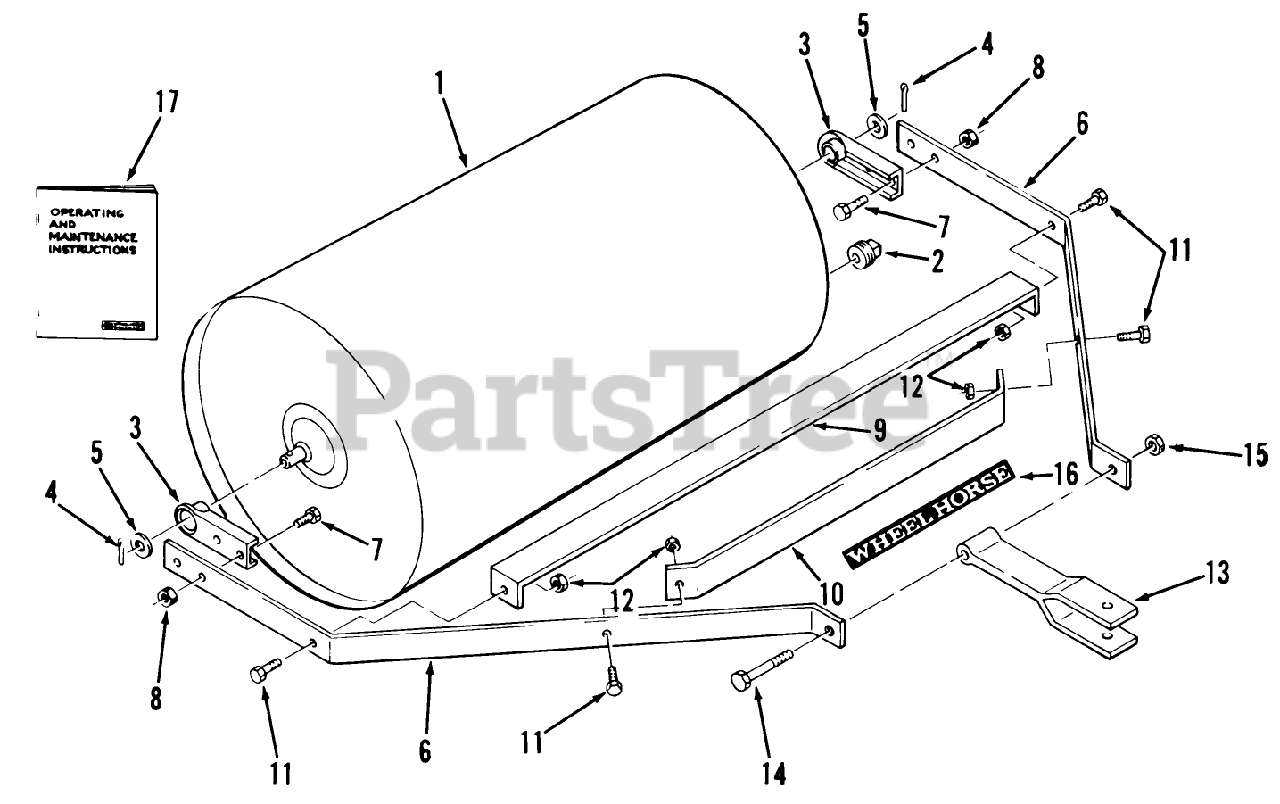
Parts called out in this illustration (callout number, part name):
1	Drum Assembly
2	Pipe Plug
3	Hub (w/Bushing)
4	Pin-Cotter
5	WASHER
6	Frame Side Bar
7	Bolt
8	Nut
9	Scraper Bar
10	Frame Support
11	BOLT
12	NUT
13	HITCH ASSEMBLY
14	Bolt 1/2-13 x 3 1/2
15	Nut
16	DECAL-WHEEL HORSE
17	Operating and Maintenance Instructions
